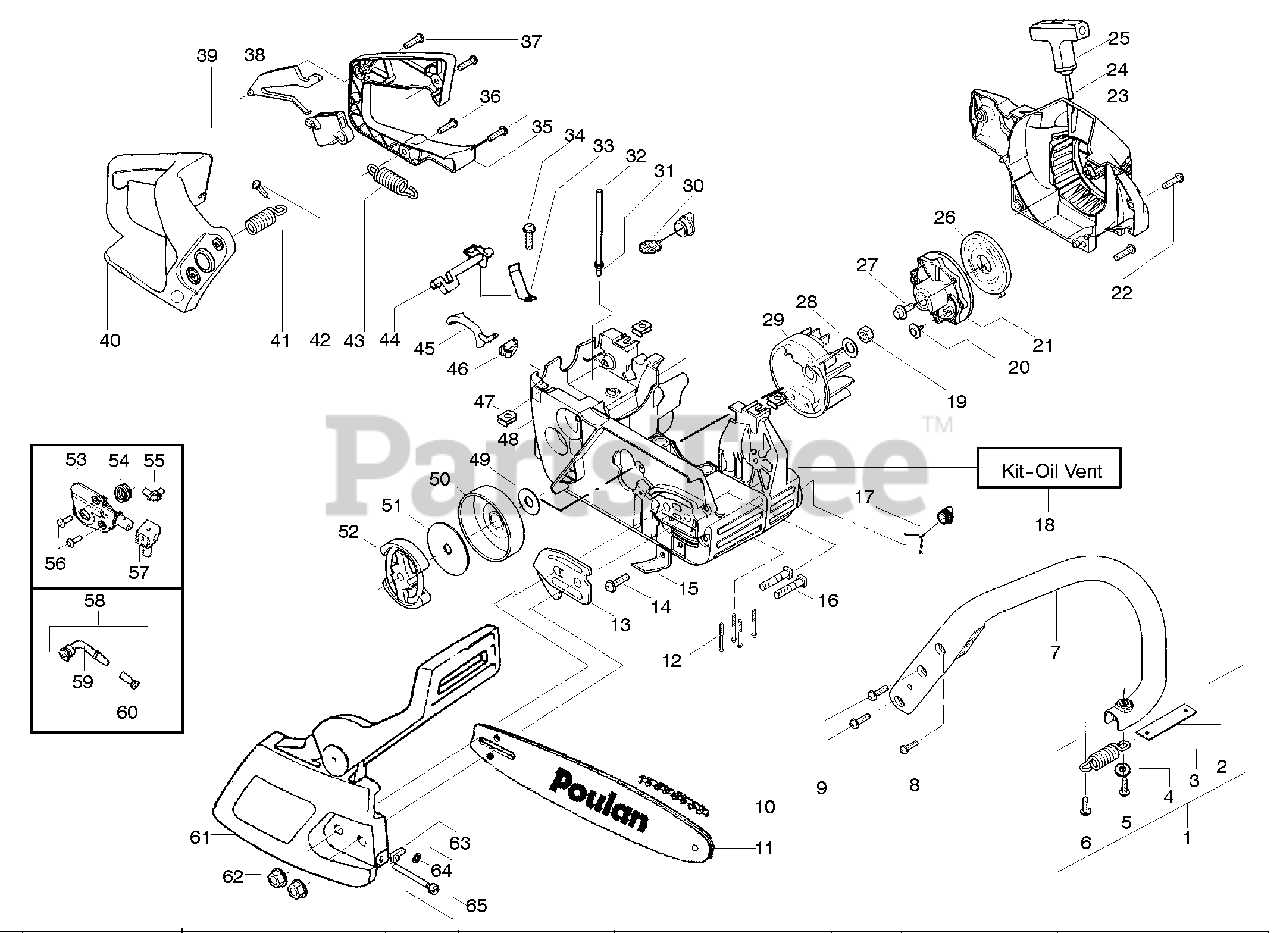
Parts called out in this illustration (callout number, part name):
1	Assy.-Isolator
2	Limiter Strap
3	Spring-Isolator
4	Washer
7	Front Handle
10	Chain-18"
13	Plate-Bar Mount.
15	Chain Catcher
21	Starter Pulley
25	Handle-Starter
26	Spring-Recoil
28	Washer-Flywheel
29	Assy-Flywheel
30	Assy-Fuel Cap
31	Fitting-fuel line
32	Kit-Fuel line (large)
33	Spring-Switch
35	Cover-Rear Handle
38	Throttle Lockout
39	Trigger-Throttle
41	Kit-Isolator (Upper)
43	Spring-Isolator
48	Assy-Chassis fuel lines and caps
49	Washer-Thrust
50	Assy.-Clutch Drum w/bearing
51	Washer-Clutch
53	Kit-Oil Pump
54	Gear-Worm Spring
55	Elbow-Oil Pickup
58	Assy-Oil Pick-up
59	Pick-up Oiler
61	Assy.-Chain Brake
62	Nut-Bar Mounting
63	Pin-Bar Adjust
65	Kit-Bar Adjusting
